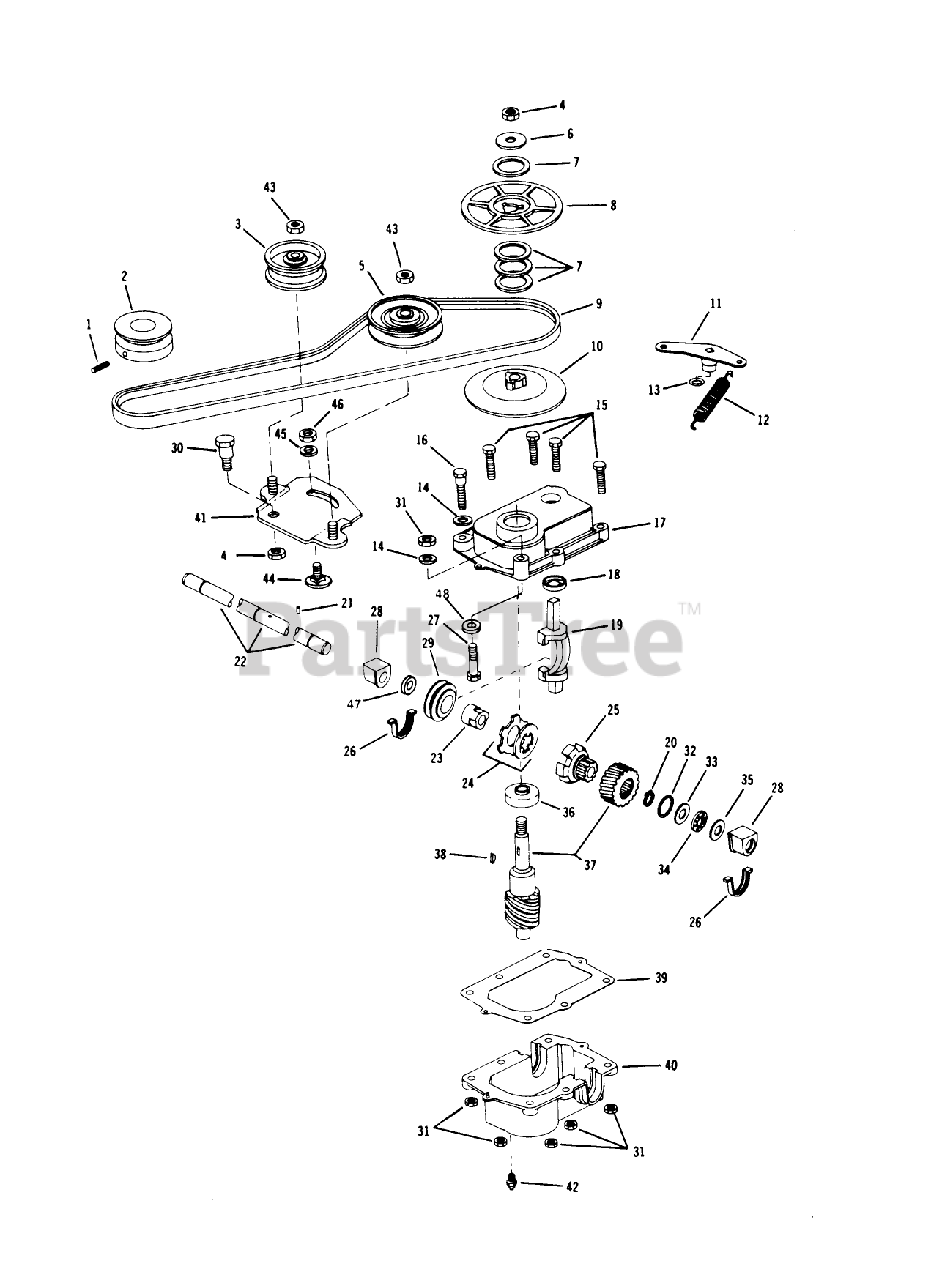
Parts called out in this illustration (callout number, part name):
1	SET SCREW F
2	PULLEY ENG F
3	PULLEY NEWHAM IND *B
4	LOCKNUT
5	IDLER NEW HAM IND
6	WASHER
8	PULLEY UPPER PL
9	V-BELT
10	PULLEY LOWER PL
12	SPRING
13	O-RING
18	GUIDE ELCO
20	RET RING
21	PIN DRIVE LOCK
25	DRIVER BROCKWAY
28	BEARING & SEAL AY (12)
31	LOCKNUT E
33	WASHER-THRUST
35	THRUST WASHER
36	BEARING-BALL
38	KEY GALGER
39	GASKET HOOSIER
42	FITTING LINCOLN
43	NUT-JAM, LOCKING
45	WASHER M
46	NUT-LOCK F
47	WASHER
